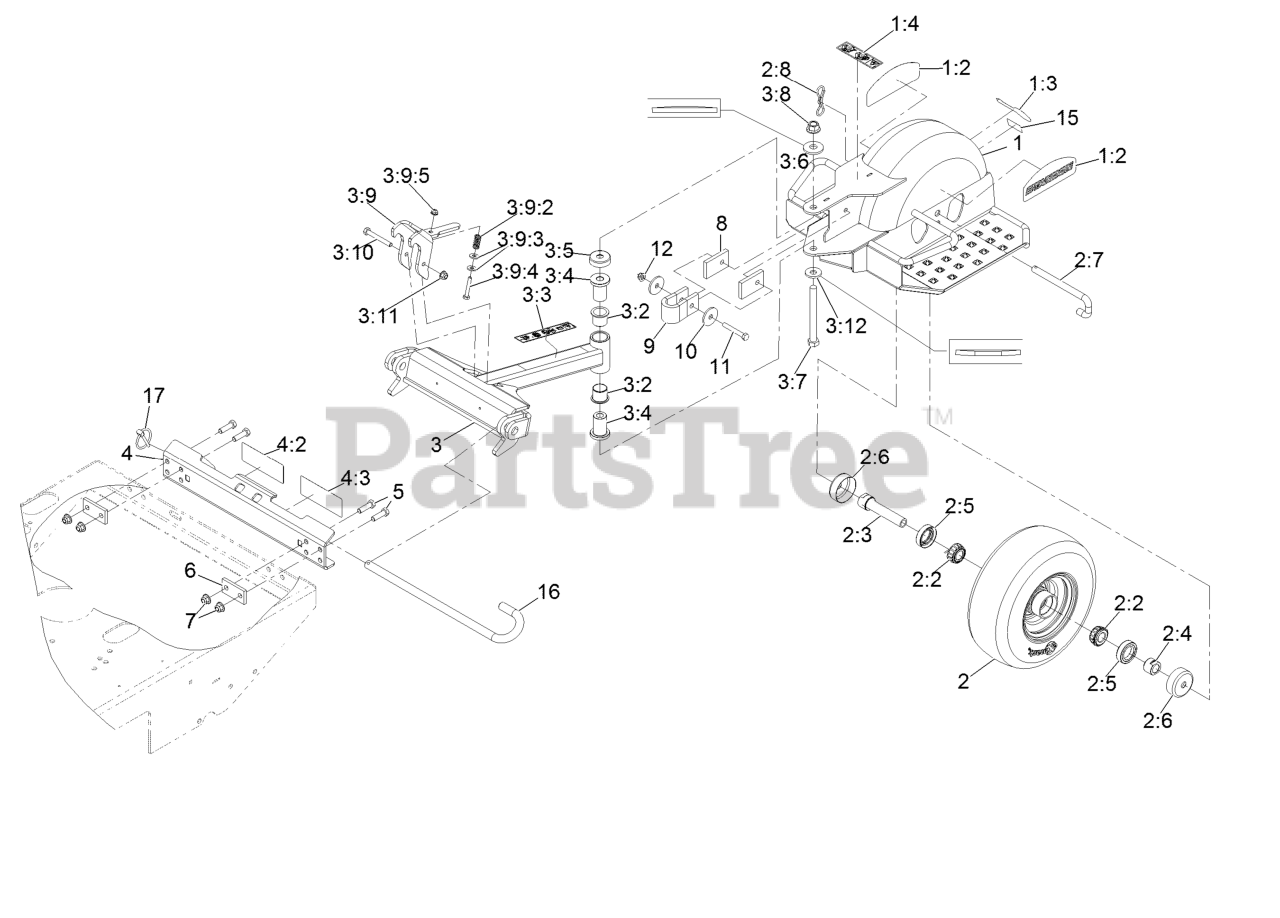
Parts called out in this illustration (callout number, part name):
1	ASM-Sulky Frame W/ Decals
1:2	Decal, Standon
1:3	Decal, Exmark
1:4	Decal-Warning Hand Pinch
2	ASM, Wheel And Bearings
2:2	Bearing-Cone Tapered Roller
2:3	Caster Axle ASM
2:4	Spacer-Nut
2:5	Seal-Double Lip
2:6	Guard-Seal
2:7	Pin, Caster
2:8	Pin-Cotter, Locking
3	ASM, Draw Bar
3:2	Bushing-Pivot
3:3	Decal-Sulky Hazard
3:4	Spacer, Pivot
3:5	Cover, Dust
3:6	Washer-Belleville
3:7	Screw-HH 1/2-13 X 5
3:8	Nut-Lock 1/2-13
3:9	Transport Latch ASM
3:9:2	Spring, Compression
3:9:3	Washer-1/4 Std
3:9:4	Screw-HH
3:9:5	Nut-Nyloc 1/4-20 Flg
3:10	Screw-HH 5/16-18 X 2 1/2
3:11	Nut-Nyloc 5/16-18 Flg
3:12	Washer-Spring Disc 1/2
4	ASM, Mount Plate
4:2	Decal-Belt Drive Warning
4:3	Decal-Warning, Sulky
5	Screw-HH 3/8-16 X 1 1/4
6	Plate, Back-Up
7	Nut-Nyloc 3/8-16 Flg
8	Pad, Stop
9	Stop, Rotation
11	Screw-HH 5/16-18 X 2 1/4
12	Nut-Nyloc 5/16-18 Flg
15	Decal-Patent
16	Pin, Pivot
17	Pin-Lynch
